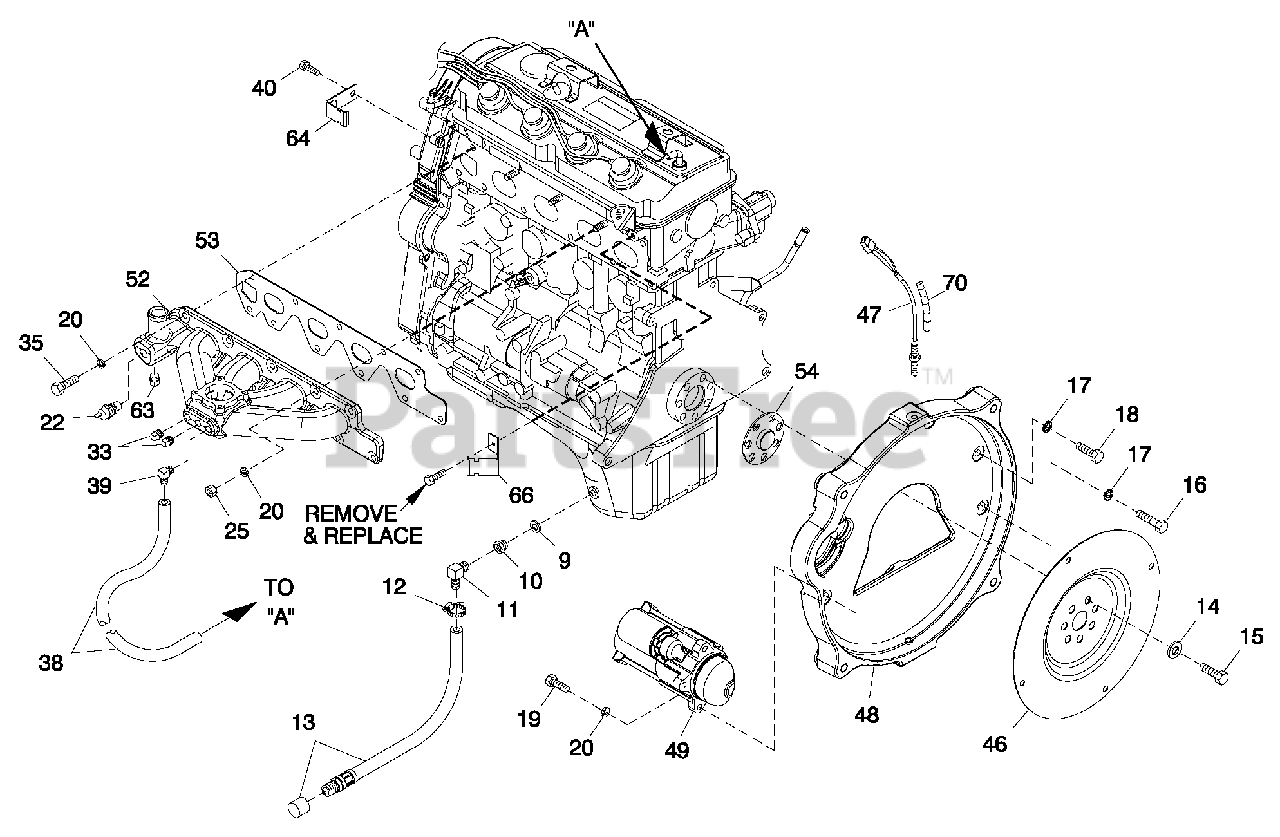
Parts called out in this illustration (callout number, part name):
6	SPACER DC ALTERNATOR P U LLEY
9	WASHER NYLON .565
10	ADAPTER M14-1.50X 3/8 NPT
11	BARBED EL 90 3/8 NPT X 3/8
12	CLAMP HOSE .38-.87
13	HOSE DRAIN ASSY 28"
14	WASHER FLAT .531 IDX 1.062 OD
15	SCREW HHC M12-1.25 X 20 G10.9
16	SCREW HHC M10-1.25 X 45 G8.8
17	WASHER SHAKEPROOF EXT 7/16 STL
18	SCREW HHC M10-1.25 X 30 G8.8
19	SCREW SHC M8-1.25 X 30 G12.9
20	WASHER LOCK M8-5/16
22	SWITCH HI-TEMP245DX3/8 NPT (R-PANEL)
25	N U T HEX M8-1.25 G8 CLEARZINC
33	PL U G STD PIPE 1/4 STEEL SQ HD
35	SCREW HHC M8-1.25X 25 G10.9
36	FILTER 1.5L/2.4LG2 OIL
38	HOSE 3/8 ID SINGLE BRAID (15" LG)
39	BARBED EL 90 1/4 NPT X 3/8
40	SCREW HHC M6-1.0X 25 G8.8
44	GASKET EXHAUST MANIFOLD
46	FLEX PLATE 2 POLE 2.4LG2
47	ASSY MAGPICK U P(3/8-24 MALE)
48	ADAPTER ENGINE 2.4L MACHINE
49	STARTER MOTOR 12V
53	GASKET INTAKE MANIFOLD
54	SPACER 2.4L G2 FLEX PLATE
60	POLY V-BELT G2 (3600 RPM)
63	PLU G STD PIPE 3/8 STEEL SQ HD
64	BRACKET, SIGNAL CONDITIONER
66	BRACKET SIGNAL CONDITONER
70	COND UIT FLEX .25"ID
